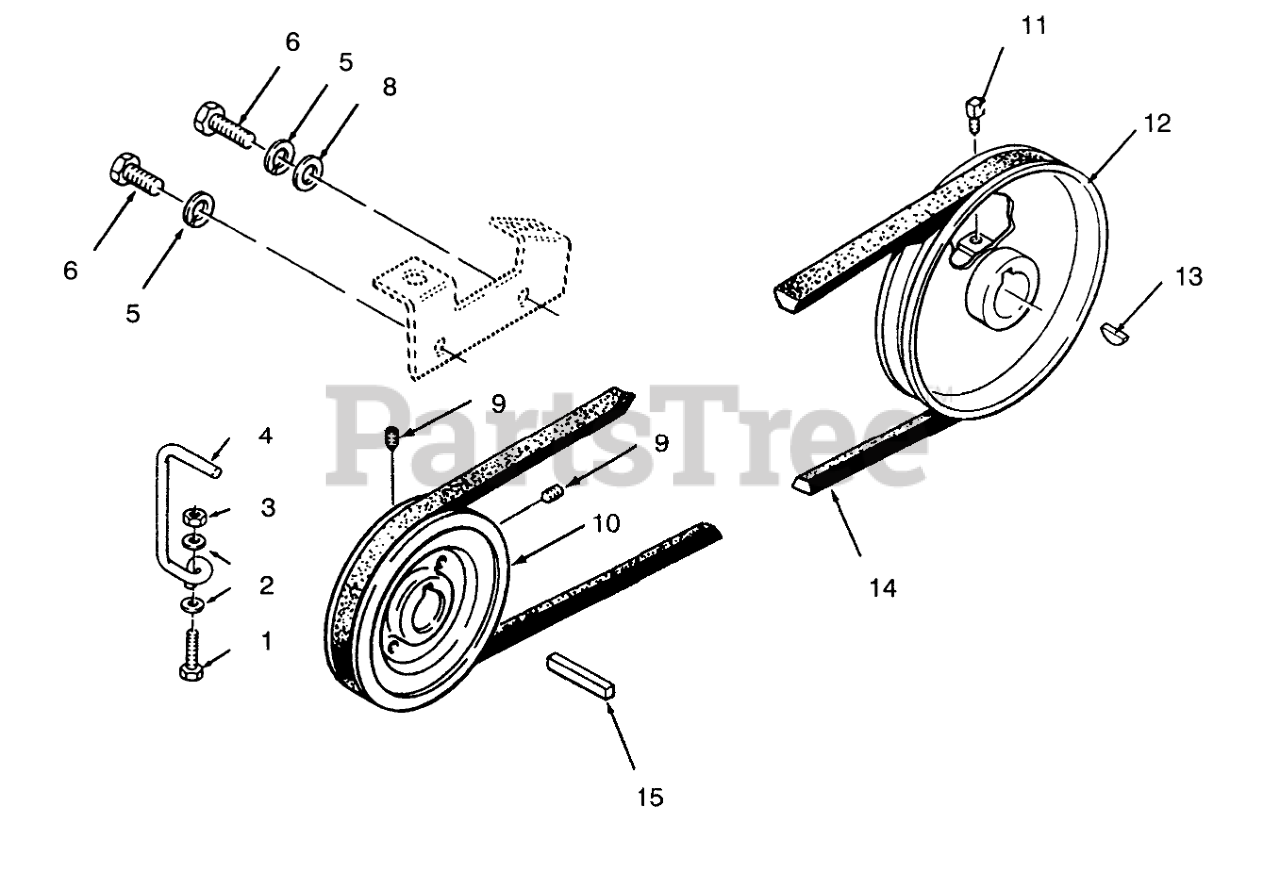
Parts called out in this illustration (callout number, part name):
1	SCREW-HH
2	WASHER-FLAT
3	NUT-LOCK, NI
4	GUIDE-BELT BOTTOM
5	WASHER-LOCK
6	SCREW-HH
8	WASHER-FLAT
9	SCREW-SET, HSH
10	PULLEY
11	SCREW-SQH
12	PULLEY-TRANSMISSION
13	KEY-HI PRO
14	Belt-Drive
